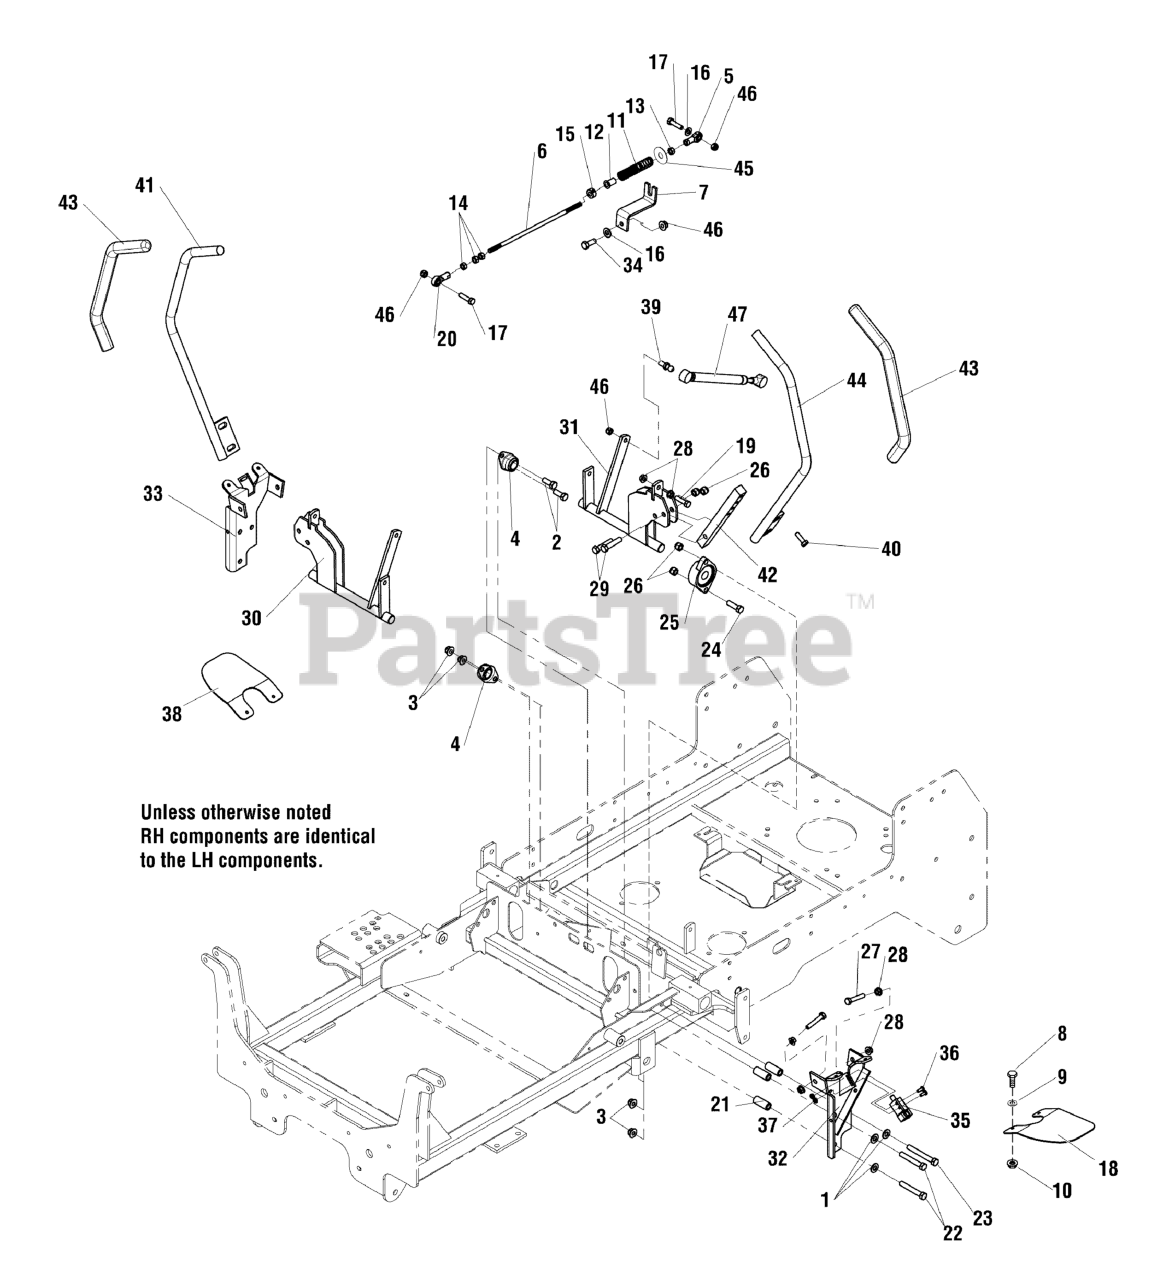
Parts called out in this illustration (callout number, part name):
1	WASHER, 3/8 SAE
2	BOLT, 3/8-16 X 1" GD5 CZ
3	NUT, 3/8-16 HEX NYLOCK FLANGE
4	BEARING, BRONZE FLANGE, 3/4
5	BALL JOINT 5/16-24 LH FEMALE BRONZE RACE
6	ROD, HYDRO LINKAGE
7	MOUNT, REVERSE RETURN - BLK
8	BOLT, 1/4-20 X 3/4 GD5 YZ
9	WASHER, 1/4 SAE
10	NUT, 1/4-20 HEX NYLOCK FLANGE
11	SPRING, REVERSE RETURN
12	BUSHING, NYLON
13	NUT, 5/16-24 HEX, LH
14	NUT, 5/16-24 HEX
15	COLLAR, 5/16 SET
16	WASHER, 5/16" SAE
17	BOLT, 5/16-18 X 1-1/4 GD5 YZ
18	PLATE, HAND GUARD, LH - BLK
19	BOLT, 5/16-18 X 1-1/8 GD5
20	BALL JOINT 5/16-24 RH FEMALE BRONZE RACE
21	SPACER, .39 X .63 X 1.50
22	BOLT, 3/8-16 X 2-1/2" GD5 CZ
23	BOLT, 3/8-16 X 3" GD5 CZ
24	BOLT, 3/8-16 X 1-1/4" GD5 CZ
25	BEARING, FLANGE
26	NUT, 3/8-16 HEX NYLON LOCK
27	BOLT- 5/16-18 X 1-3/4 GD5 TFL
28	NUT, 5/16-18 HEX SERRATED FLANGE (LARGE)
29	BOLT, 3/8-16 X 1-3/4" GD5 CZ
30	SHAFT, Control
31	WELD, CONTROL SHAFT, LH - BLK
32	WELD, NEUTRAL LOCK, LH - BLK
33	WELD, NEUTRAL LOCK, RH - BLK
34	BOLT, 5/16-18 X 1 GD5 YZ
35	SWITCH, PLUNGER, N.O.
36	SCREW- #10-24 X 1/2 ROUND PHILLIPS
37	NUT, #10-24 HEX
38	PLATE, HAND GUARD, RH - BLK
39	10MM BALL STUD, 5/16-18 X 3/4 THDS
40	SCREW, 5/16-18x0.750, GR5, WHIZ-LOCK, ZC
41	WELD, HANDLE MOTION CONTROL RH - BLK
42	MOUNT, CONTROL ARM - BLK
43	GRIP, FOAM, 3/4 ID, 16 LONG
44	WELD, HANDLE MOTION CONTROL LH - BLK
45	WASHER, 3/8 X 1 X 1/16, NYLON F/W
46	NUT, 5/16-18 HEX NYLOCK FLANGE
47	DAMPENER, CONTROL,#(P6709/P3610)
